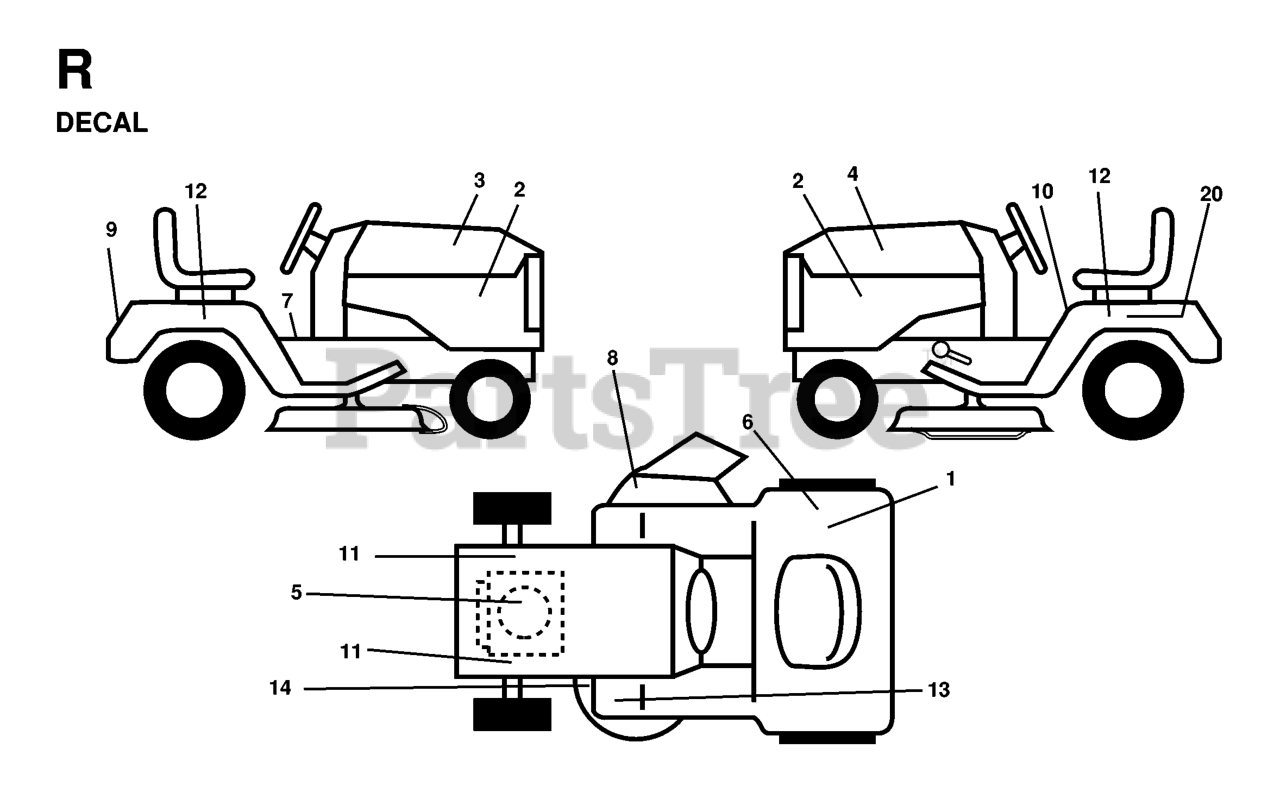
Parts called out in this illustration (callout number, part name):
1	DECAL
2	DECAL PNL SIDE
4	DECAL
5	DECAL HP ENGINE
6	DECAL EUROPE STANDARD CE
7	DECAL PARK BRAKE
8	DECAL MOWER CUT/FINGER
9	DECAL FENDER HUSQ
10	DECAL READ OWNER'S MAN SYMS
11	DECAL
12	DECAL
13	DECAL
14	DECAL V BELT SCHEMATIC
20	DECAL BTRY SYMBOLS
